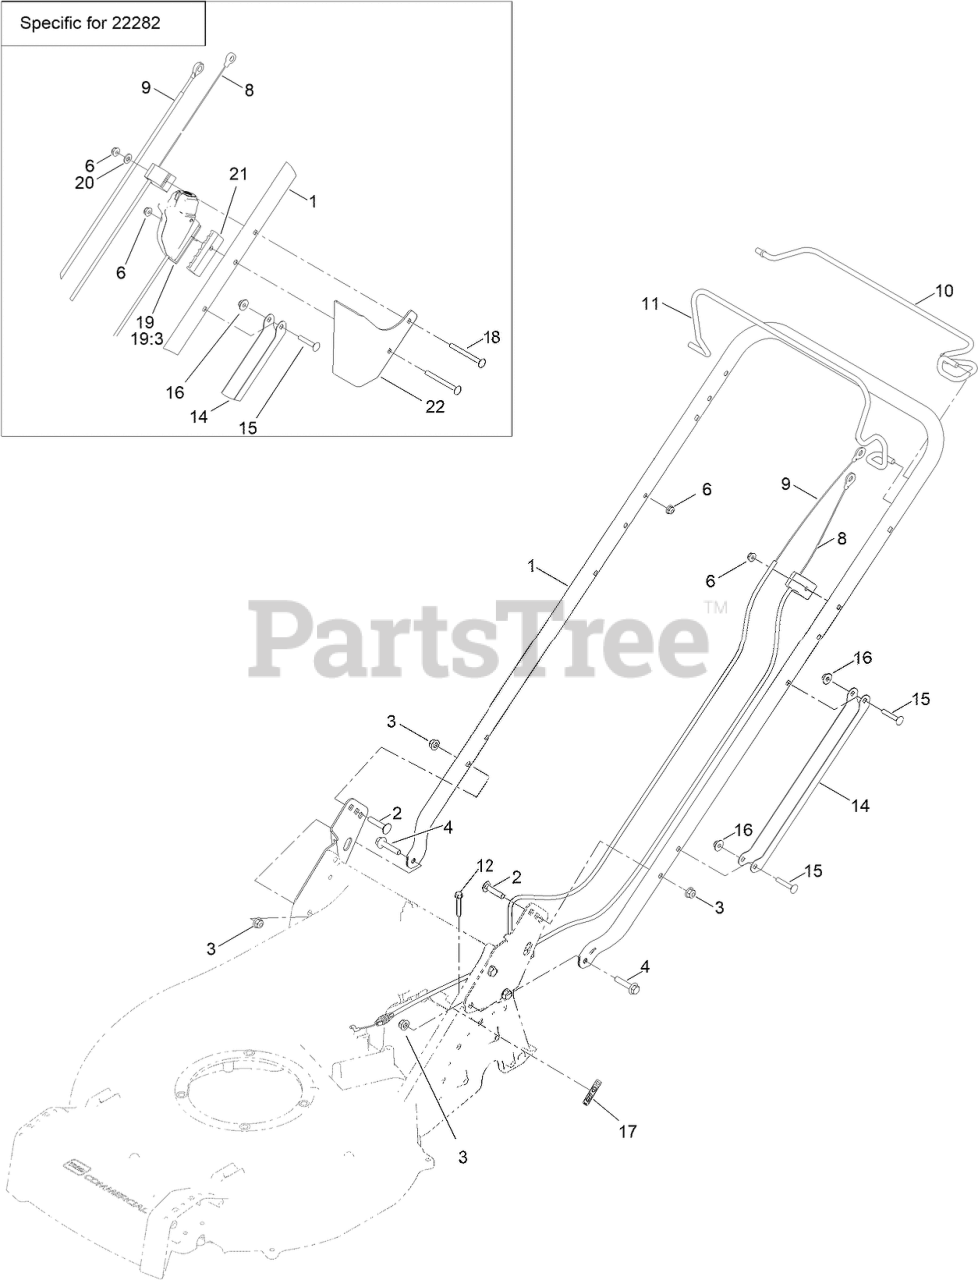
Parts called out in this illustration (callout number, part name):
2	BOLT-CARR
3	NUT-HF, NI
4	SCREW-HHF
6	NUT-HF
8	CABLE-BRAKE, 60V
9	CABLE-TRACTION
10	BAIL-TRACTION
11	BAIL-BRAKE
12	SCREW-HWH
14	GUARD-CABLE, HANDLE
15	SCREW-CARR
16	NUT-HF
18	SCREW-CARR
19	STARTER SWITCH ASM
19:3	STARTER BUTTON SERVICE ASM
20	WASHER-FLAT
21	SPACER-HOUSING, SWITCH
22	GUARD-HOUSING, SWITCH
